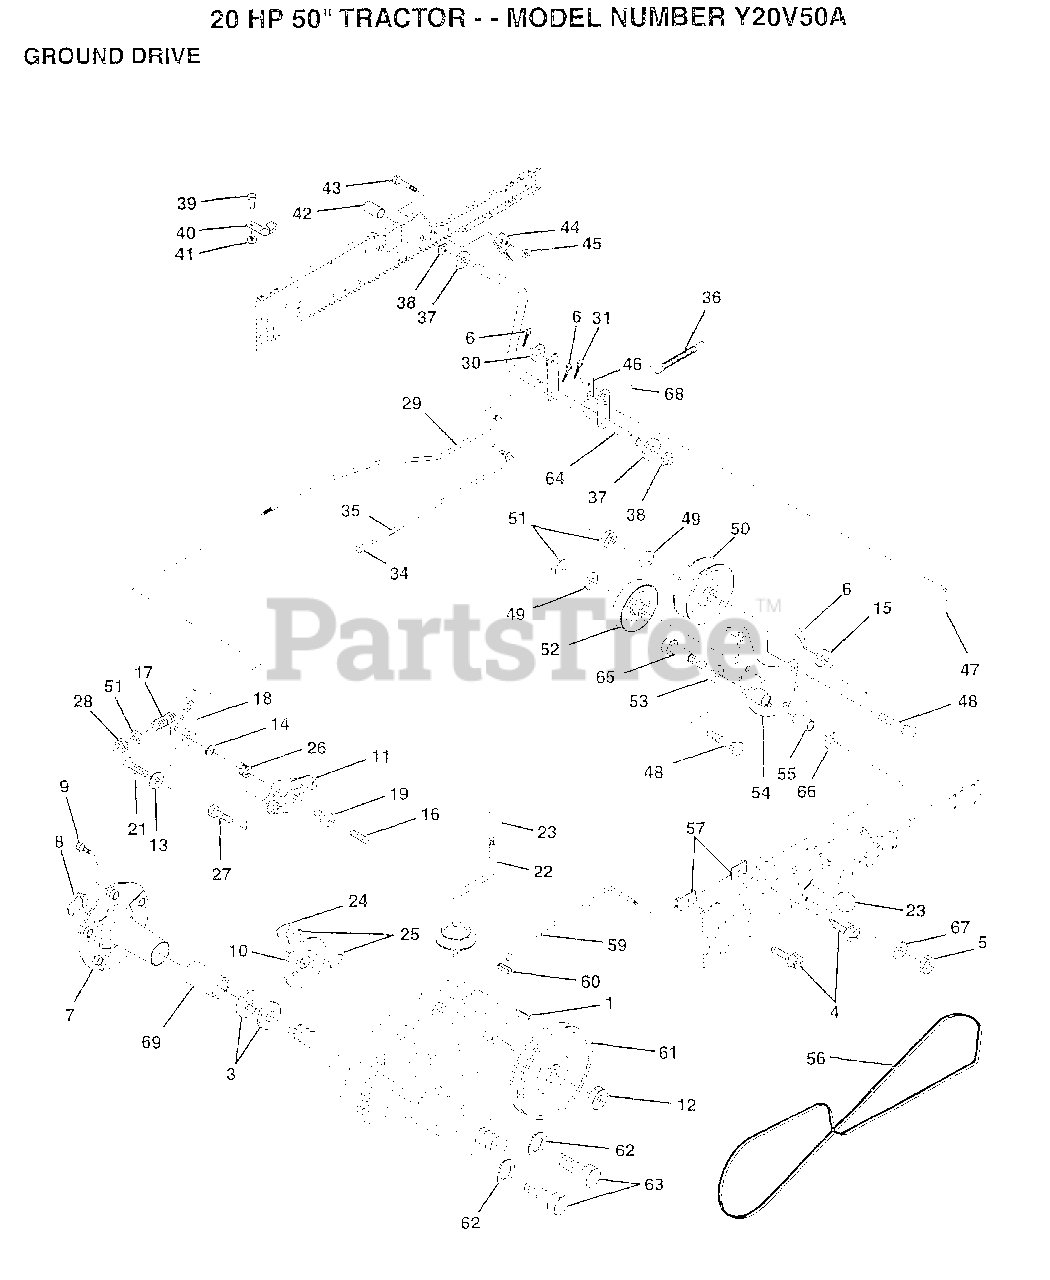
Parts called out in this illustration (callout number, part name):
3	WASHER T
4	SCREW LT
6	COTTER PIN
8	KLIP RING
9	BOLT.HUB.WHL.REAR
11	YOKE BRAKE DISC
12	NUT STD
13	WASHER SPECIAL
14	BUSHING LEVER BKT
15	WASHER
16	SCREW SET 1/4-20
17	"SPRING,ROD BRAKE"
18	LEVER BRAKE GT
19	CAM BRAKE DISC GT
21	SCREW FLT 1/4X28
22	GEAR SHFT LVR T
23	KNOB
24	SUPPORT PUCK BRKE
25	PUCK BRAKE TOP
26	SPRING RET BRAKE
27	SCREW HX WASH
28	NUT
29	ROD BRAKE ZINC GT
30	WASHER
34	PLUNGER CAP T
35	ROD BRAKE PART GT
37	WASHER
38	NYLINER T
39	SCREW
40	ACT-SWITCH T
42	PEDAL COVER T
43	BOLT LT
44	BRKT SWITCH GT
45	NUT
46	RETAINER SPRING
47	ROD.CLUTCH
48	BOLT
49	WASHER
50	FLAT IDLER PULLEY
51	NUT
52	PULLEY.IDLER.V.GR
53	WASHER T
54	ARM.ASM.IDLER.CLU
55	"LY, BEARING"
56	BELTV.GR.DR.83.
57	BRACKET.ROD.SHIFT
59	ROD SHIFT HI LO
60	CONNECTING LINK
62	LOCKWASHER
63	BOLT
65	AXLE BOLT
66	WASHER.HARD.BLADE
67	WASHER
68	ROLL PIN STD
69	"COVER, HUB"
